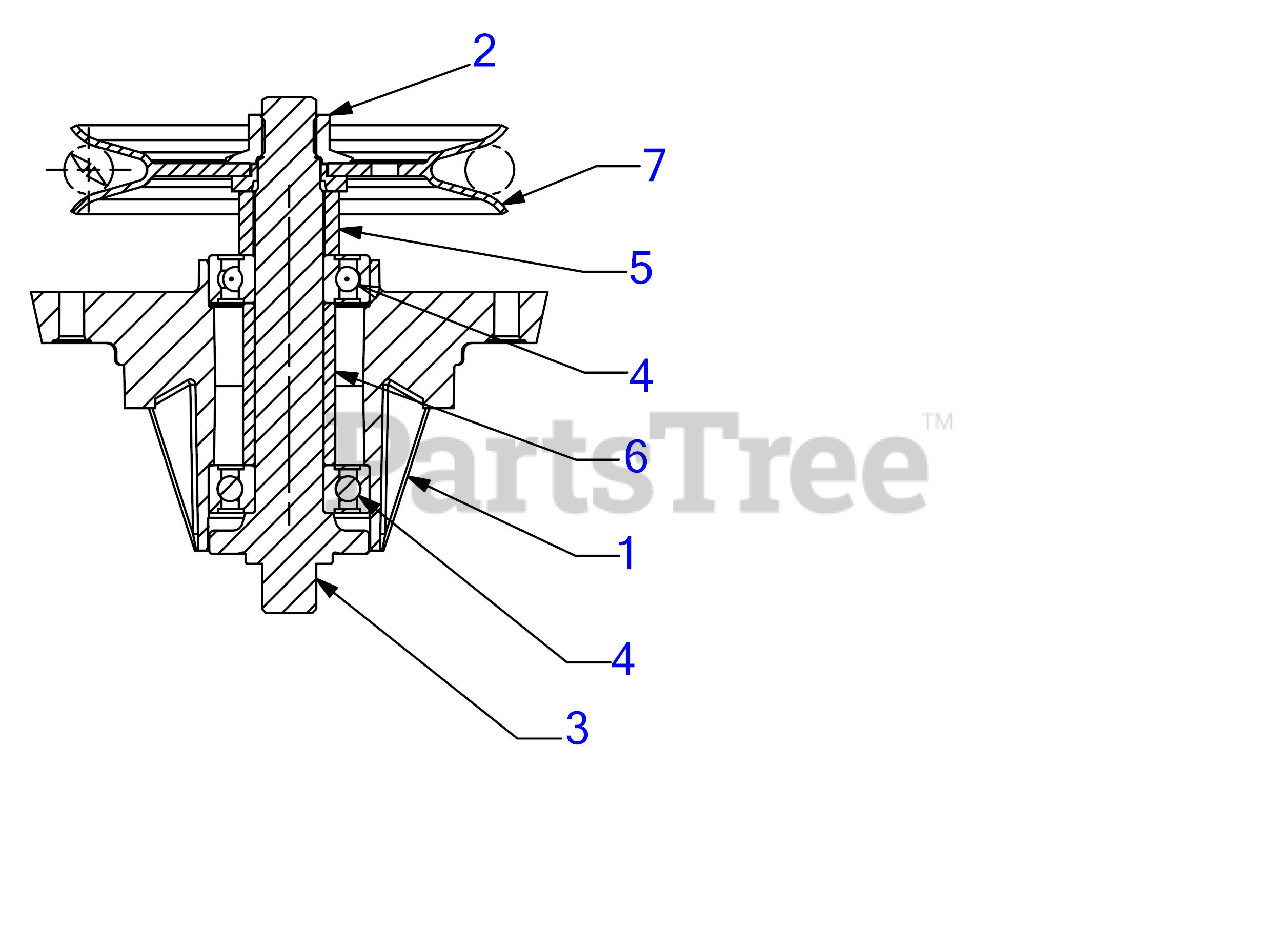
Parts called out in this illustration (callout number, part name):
1	DECK SPINDLE HOUSING
2	FLANGE NUT 5/8-18
3	SPINDLE SHAFT
4	BALL BEARING
5	SPACER .820X1.15X.730
6	SPACER- .792 x 1.060 x 1.860
7	PULLEY
